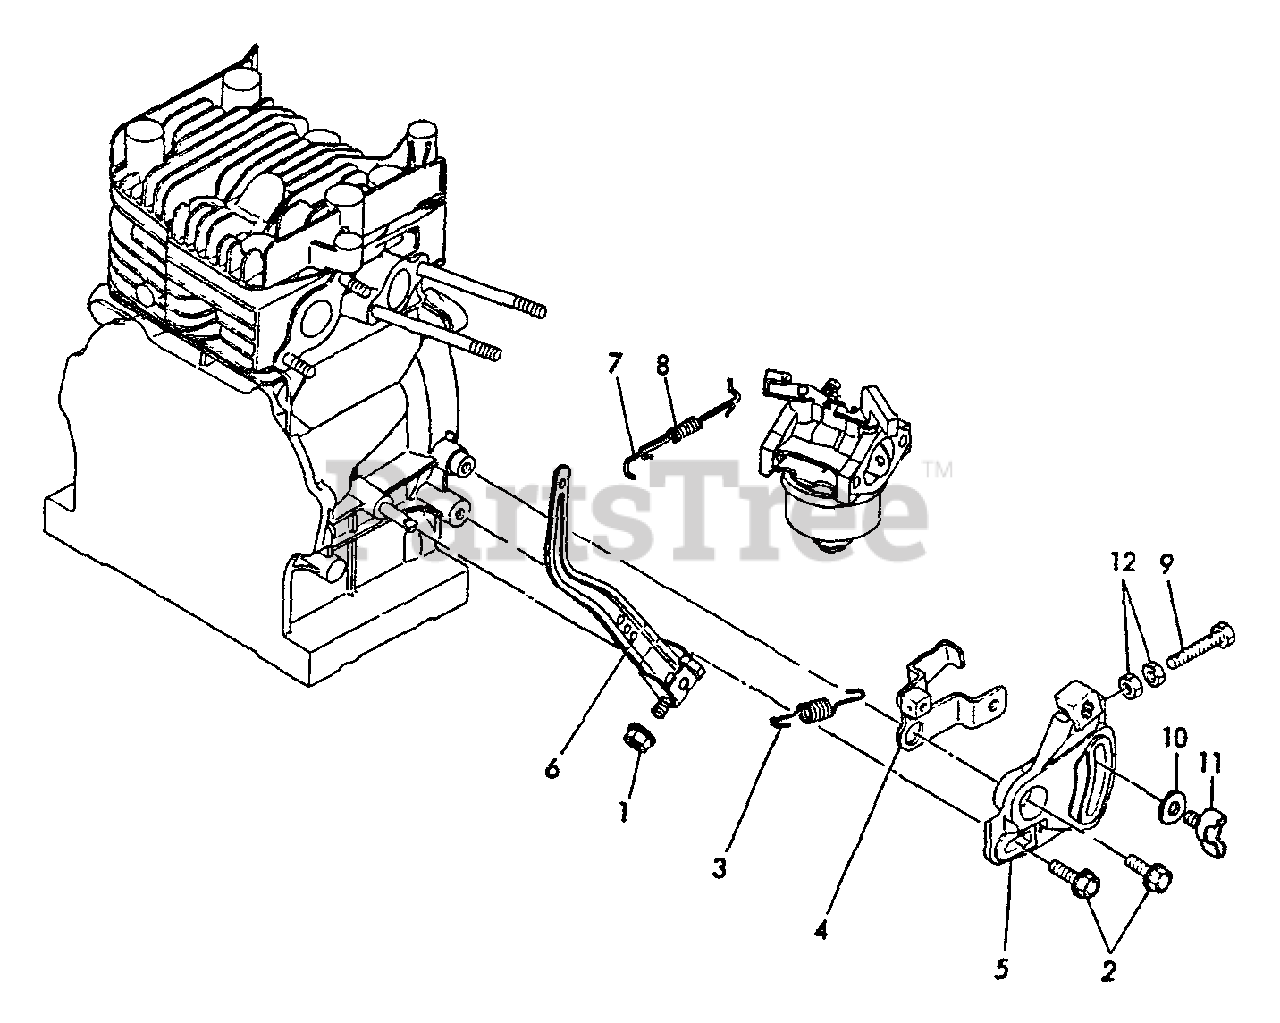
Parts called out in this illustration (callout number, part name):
1	NUT - 6 -- FLANGE
2	BOLT - 6X20
3	SPRING, REGULATOR
4	REGULATOR HANDLE ASSY
5	BRACKET, REGULATOR
6	LEVER, GOVERNOR
7	LINK, THROTTLE
8	SPRING
9	BOLT
10	WASHER - 6
11	THUMBSCREW
12	LOCKNUT - 6 -- PLATED
